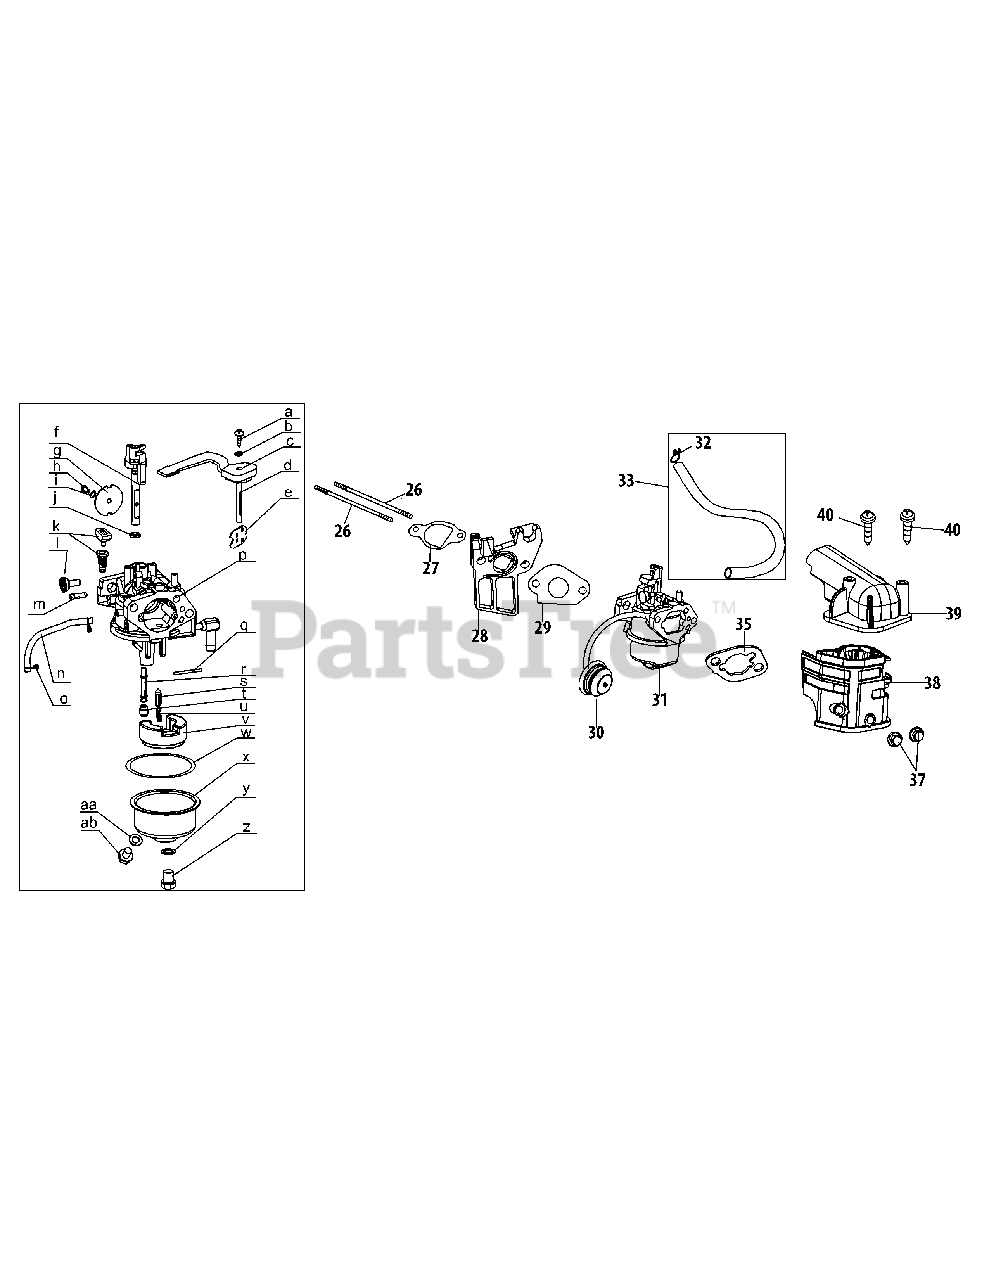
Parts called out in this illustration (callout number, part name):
26	Stud M6×110
27	Carburetor Insulator Gasket
28	Carburetor Insulator
29	Carburetor Gasket
30	Primer Assembly
30	Primer Bulb
31	Carburetor Assembly
32	Fuel Hose Clamp
33	Fuel Line Kit
35	Carburetor Gasket Plate
38	Air Cleaner Housing
39	Air Cleaner Assembly
40	Self-Tapping Bolt M4.2×16
